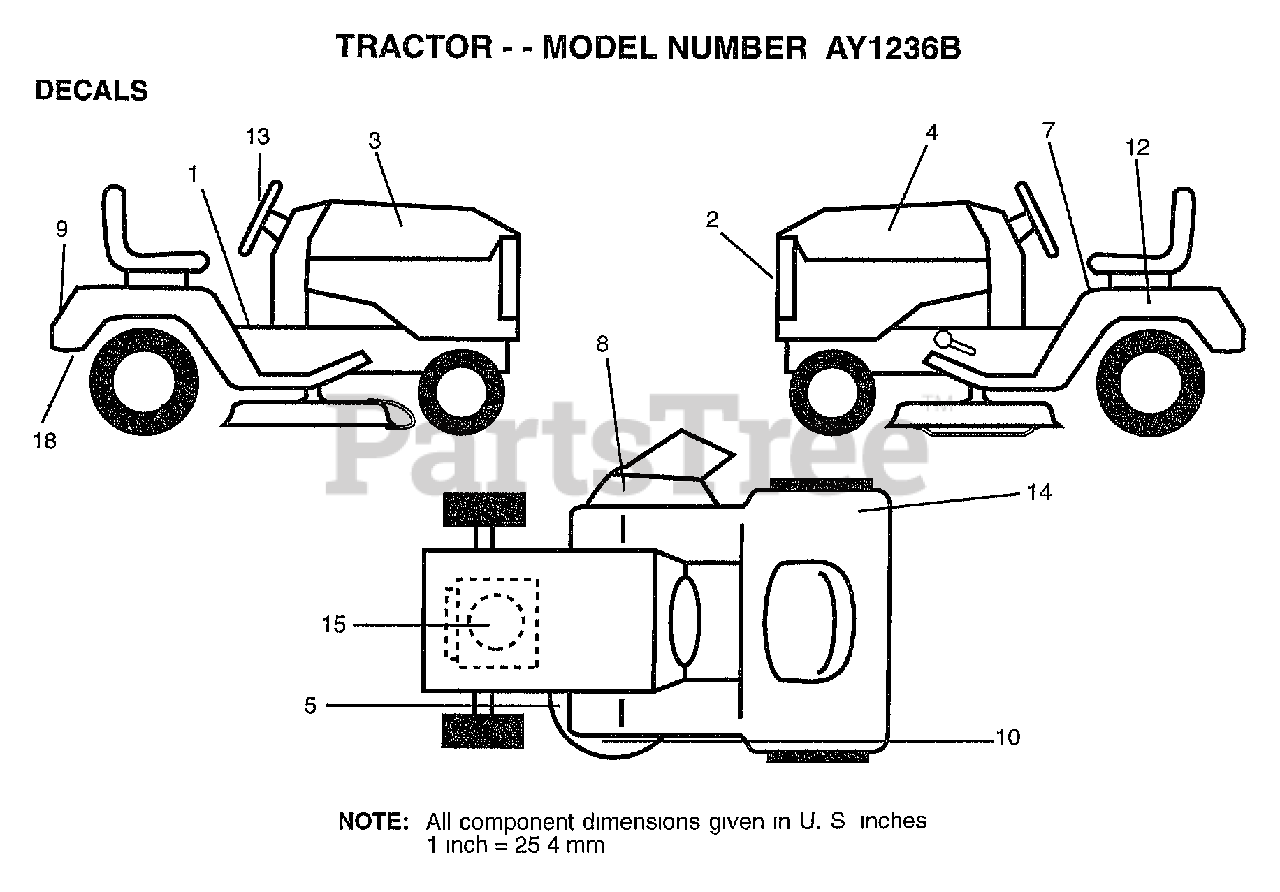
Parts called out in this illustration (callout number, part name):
1	DECAL.OP.INST.SYM
2	"DECAL,LIGHT BOX"
3	DECAL HOOD RH
4	DECAL HOOD LH
5	DECAL.V.BELT
7	DECAL.READ.O.MANU
8	DECAL.DANGER.CUTF
9	"DECAL,FENDER"
10	DECAL DECK WIZ +
12	DECAL.BTRY.DANGER
13	"DECAL,INSERT"
15	DECAL, ENGINE
18	DECAL.EURO.ST.CE.
